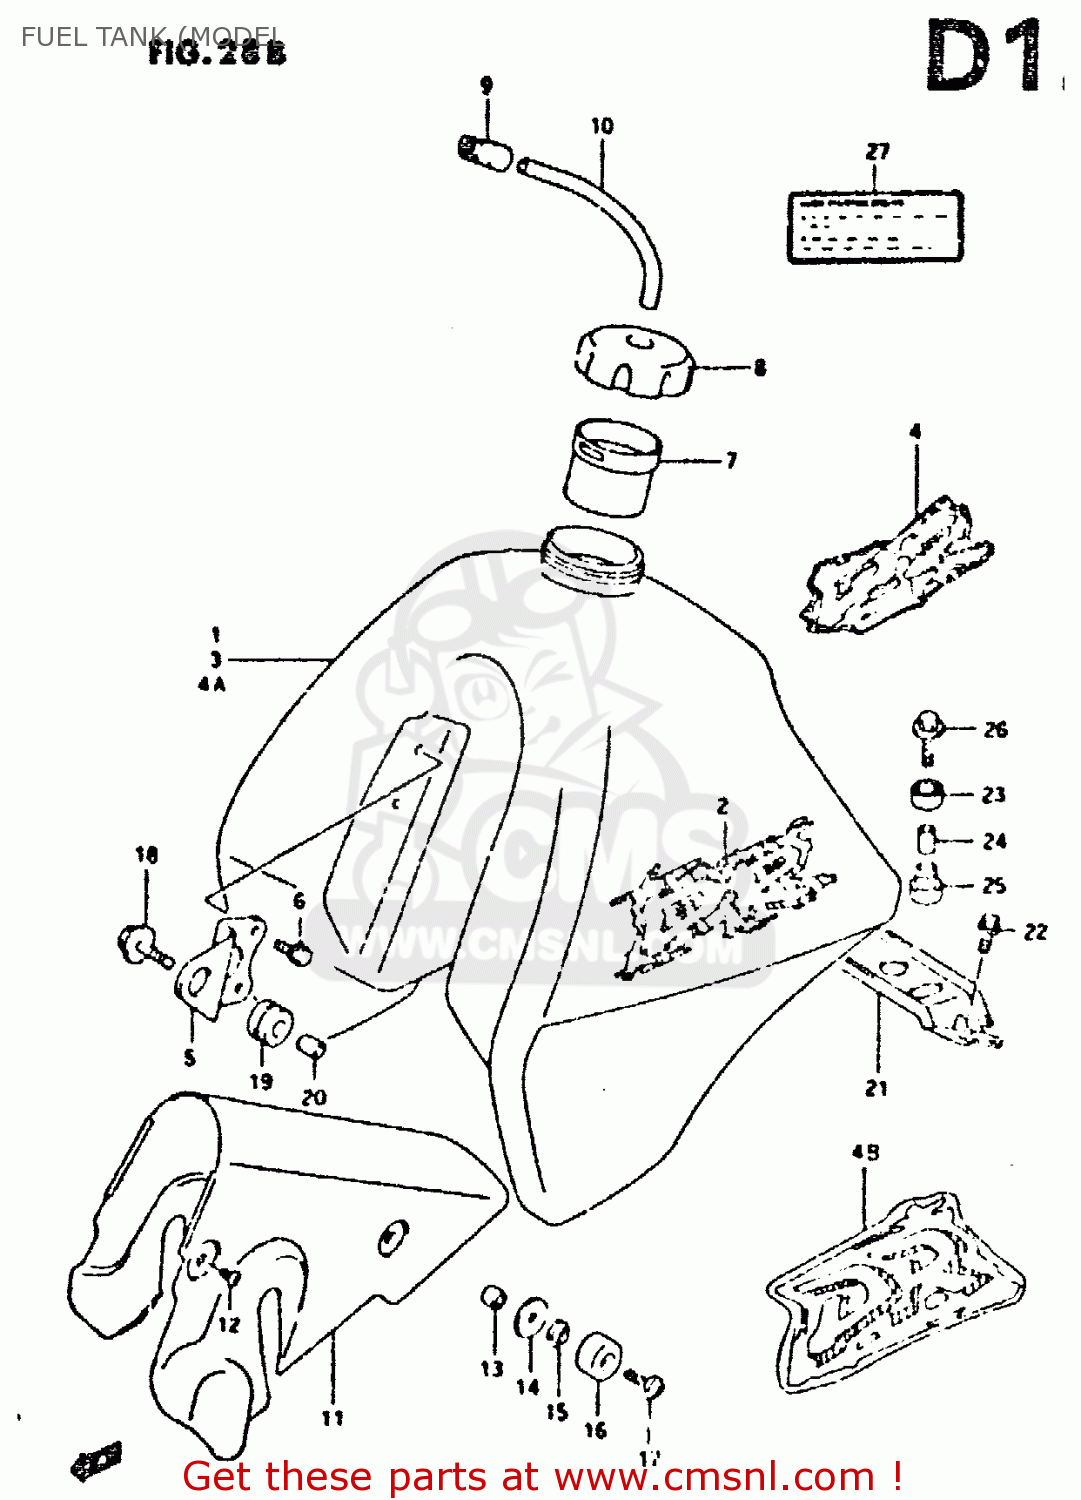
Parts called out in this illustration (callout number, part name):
1	TANK ASSY,FUEL(WHITE)
2	EMBLEM SET,FUEL TANK
3	TANK ASSEMBLY,FUEL
4	EMBLEM SET,FUEL TANK
4A	TANK ASSEMBLY,FUEL
4B	TAPE SET,FUEL TANK
5	BRACKET,FUEL TANK,FRONT
6	BOLT
7	TUBE,FILLER INLET
8	CAP ASSY,FUEL TANK
9	CLAMP,FUEL TANK BREATHER HOSE
10	HOSE(5X8.2X600)
11	HEAT SHIELD,FUEL TANK
12	BOLT
13	SPACER(6.1X14X7.2)
14	WASHER (6.5X26X2.3)
15	WASHER
16	CUSHION
17	SCREW
18	BOLT(8X25)
19	CUSHION
20	SPACER (8.8X12X12.5)
21	BRACKET,FUEL TANK RR
22	BOLT
23	CUSHION
24	SPACER
25	CUSHION
26	BOLT
27	LABEL,STARTING CAUTION
